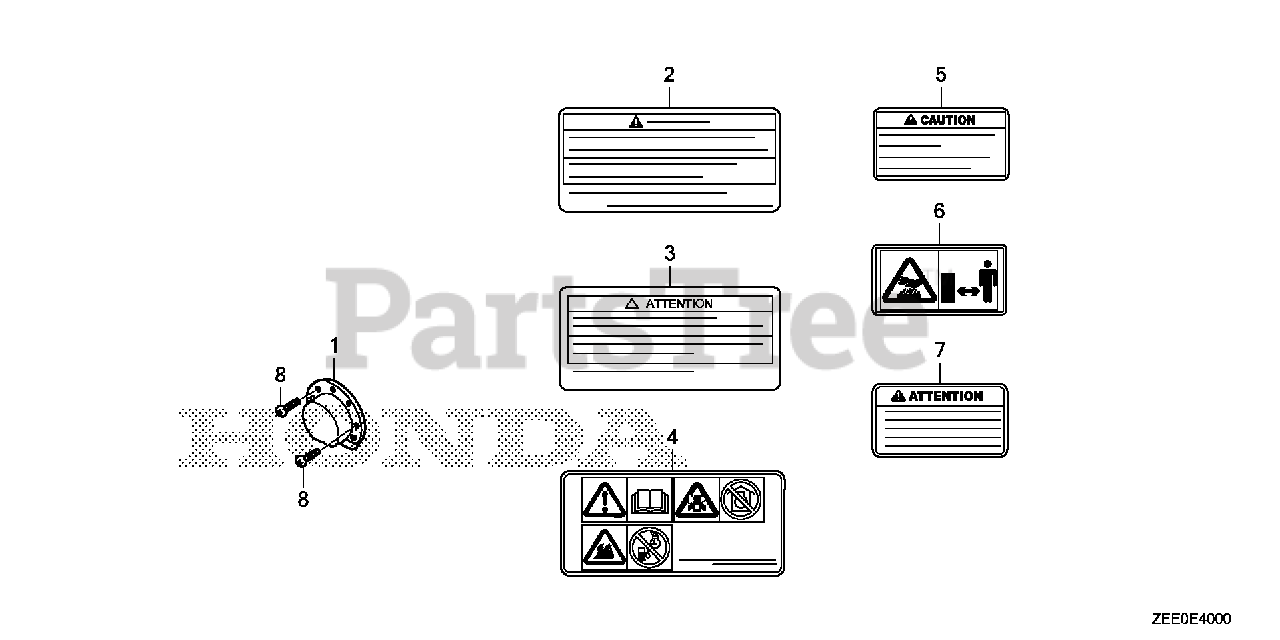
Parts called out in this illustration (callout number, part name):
2	MARK, OPERATOR CAUTION (ENGLISH)
3	MARK, OPERATOR CAUTION (FRENCH)
5	MARK, EX. CAUTION (ENGLISH)
7	MARK, EX. CAUTION (FRENCH)
